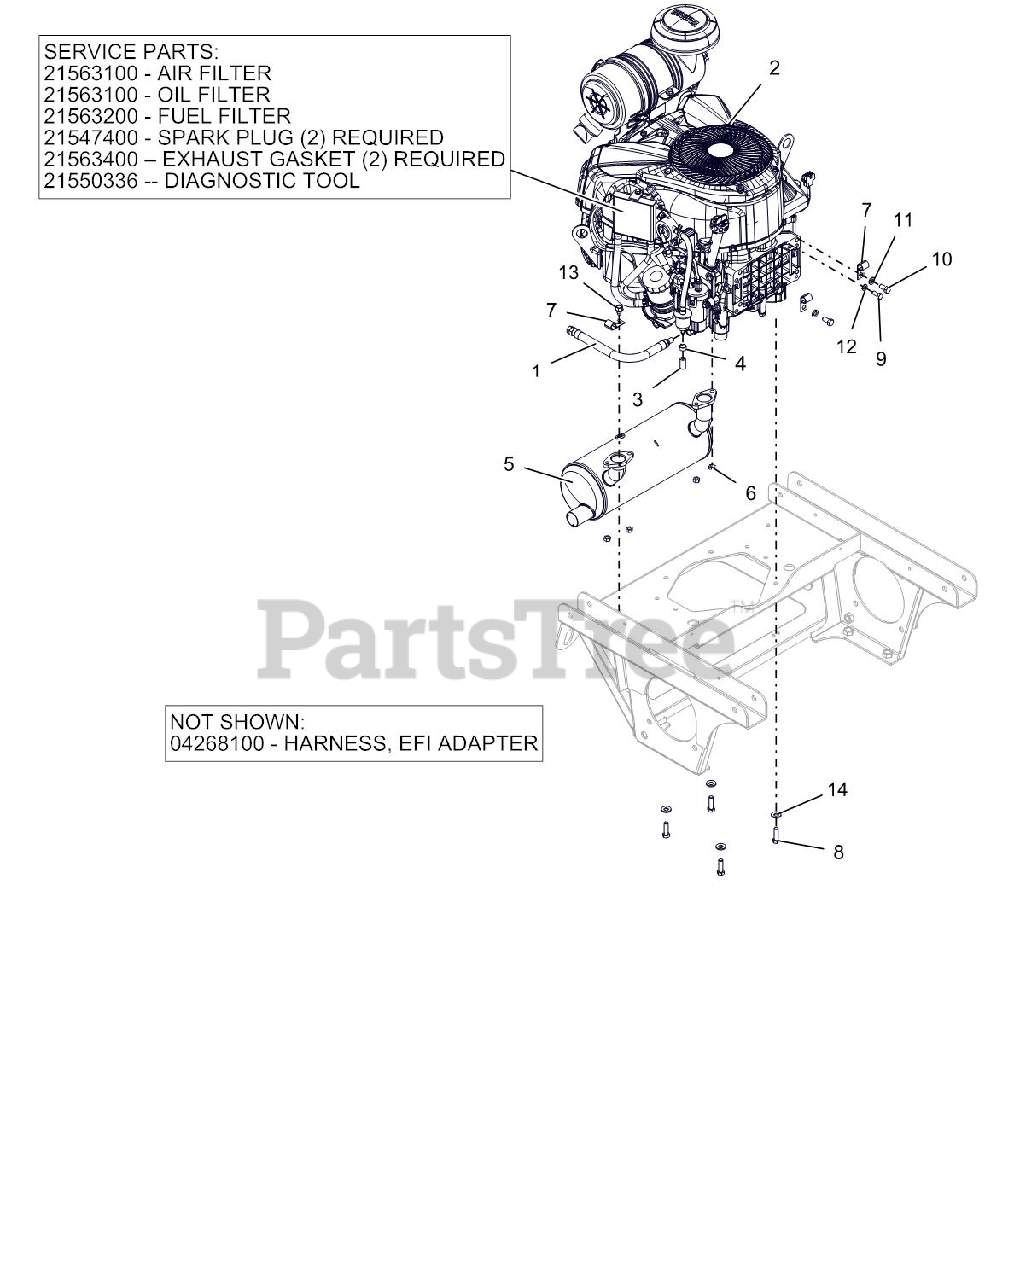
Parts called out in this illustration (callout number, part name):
1	HOSE, OIL DRAIN
2	GASKET, MUFFLER YAMAHA 824
2	FILTER-FUEL YAMAHA 824
2	AIR FILTER (OUTER) - YAMAHA
2	FILTER, OIL - YAMAHA 824
2	PLUG, SPARK
2	DIAGOSTIC TOOL, YAMAHA MXV
2	ENGINE, YAMAHA MX825V-EFI
3	HOSE, .25 LOW-PERM BULK GAS
4	CLAMP, FUEL LINE
5	MUFFLER, YAMAHA
6	NUT-LK-TOP M8-1.25 YWZC
8	BLT-HEX.38-16X1.25 G5YZ NYTORQ
9	@BLT-HEX .31-18X.75 GR5 YWZC
10	@BLT-HEX .38-16X.75 GR5 YWZC
11	@WSHR-LK .38X.094 REG YWZC
12	@WSHR-LK .31X.078 REG YWZC
13	@SCR-TAP .38-16X.50 HWH TR YWZ
14	WASHER, 3/8" SPRING DISC
15	HARNESS, EFI ADAPTER
